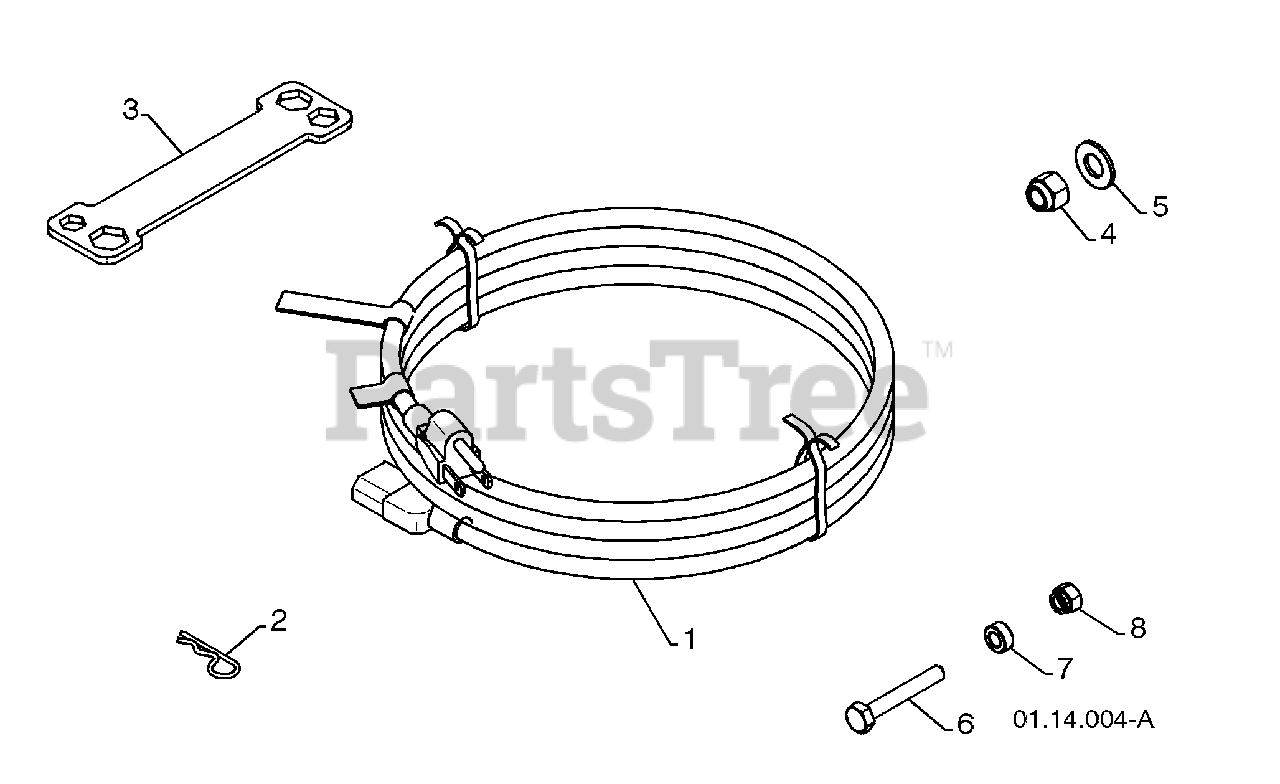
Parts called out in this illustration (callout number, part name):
1	POWER CORD
2	RETAINER PIN
3	WRENCH
4	LOCKNUT 3/8-16
5	WASHER 3/8
6	SHEAR BOLT 1/4-20 X 1-3/4
8	LOCKNUT 1/4-20
